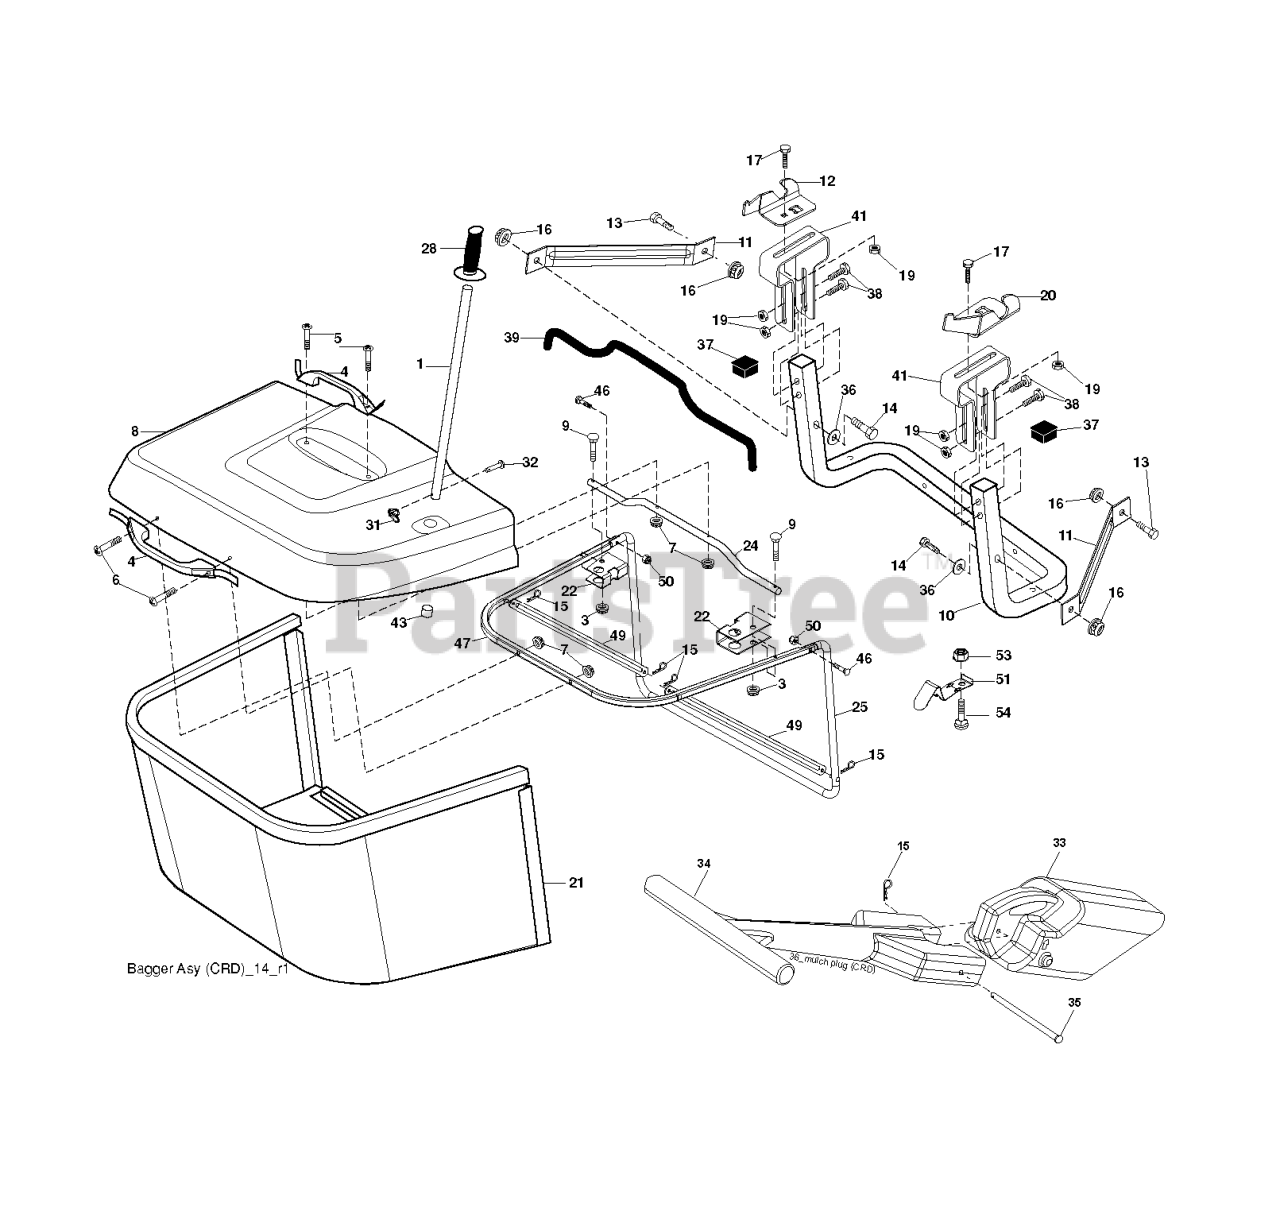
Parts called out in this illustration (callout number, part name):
1	TUBE HANDLE
3	NUT T
4	HANDLE.BAGGER.W/LVRS.BLK.CRD
5	SCREW.PAN.HEAD
6	REPL BY 532 75 00-29
8	COVER.PNT.BGR.CRD.WSLOTS.MS668
9	Bolt Carriage 1/4-20 x 2.25d x Gr.5
10	TUBE
11	BRACKET.SUPPORT.UPPER.BAG.CRD
12	BRKT PIVOT
14	BOLT-HEX EAK
15	RETAINER-SPRNG RB
16	NUT LOCK FLG 3/8-16 UNC
17	RP BOLT 5/16-18 X3/4 ZN/YEL GR
19	NUT LOCK HEX FLANGE 5/16-18
20	BRKT.PIVOT.RH.CRD
21	BAGGER.ASM.CRD.2007
22	BRKT.SIDE.BAG.CRD
24	TUBE.PIVOT.BAG.CRD.BLACK
25	PIPE
28	GRIP.HANDLE.BLACK
31	RETAINER CLIP
32	RIVET,DRILLED
33	PLUG.MULCHER.92 CRD
34	HANDLE.MULCHER.92.CRD (2 2)
36	WASHER
37	Plug Support Bagger CRD
38	BOLT.5/16-18X2.5
39	SEAL.BAGGER.CRD
41	BRKT.VERT.ADJ.BAGGER.CRD
43	PLUG, TUBING END
46	BOLT.CARRIAGE.5/16-18
47	PIPE
49	ROD
50	NUT.71038.31-18.HEX.NYLOCK
51	LATCH
53	NUT
54	BOLT
